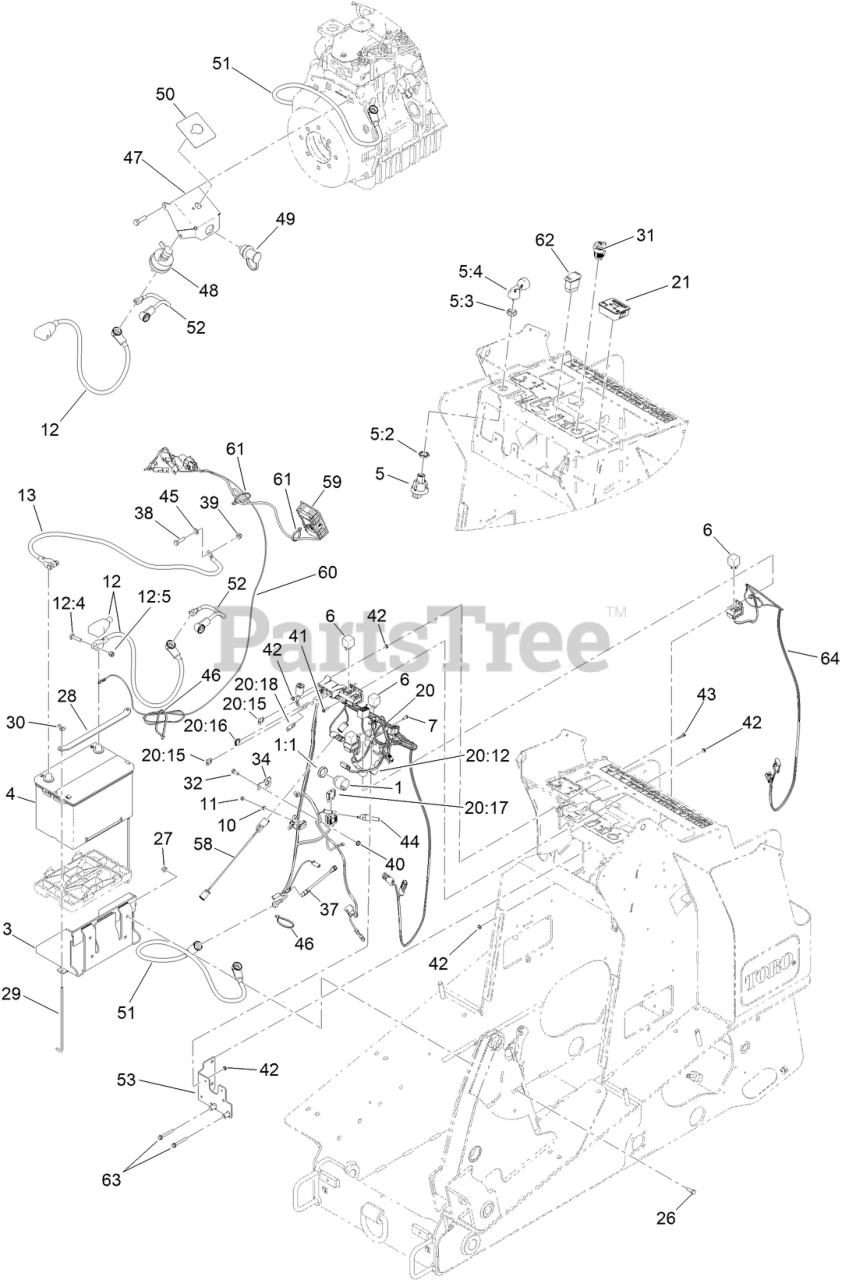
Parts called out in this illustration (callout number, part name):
1	AUDIO ALARM ASM
1:1	NUT-PLASTIC, KNURLED
3	TRAY-BATTERY
4	BATTERY
5	IGNITION SWITCH ASM
5:2	NUT-HEX
5:3	NUT-FACE
5:4	SET-KEY, IGNITION
10	WASHER-LOCK, SPRING
11	NUT-HEX
12	CABLE-BATTERY, POS ASM
12:4	BOLT-BATTERY CLAMP, 5/16-18 UNC
12:5	NUT-CLAMP, BATTERY
13	CABLE-NEGATIVE
20	HARNESS-WIRE, TX1000
20:15	FUSE-BLADE, 10 AMP
20:16	FUSE-BLADE, 15 AMP
20:17	FUSE-BLADE, 50 AMP
20:18	CAP-PLUG
21	MODULE-HOUR METER
26	SCREW-HH
27	NUT-LOCK, NI
28	STRAP-HOLD DOWN, BATTERY
29	ROD-HOLD DOWN, BATTERY
30	NUT-WING
31	RECEPTACLE-12V
32	SCREW-HH
34	CLIP-FUSE
37	HARNESS-LINK, FUSIBLE
38	SCREW-HH
39	NUT-HF, NI
40	NUT-HF
41	SCREW-HWH
42	NUT-KEPS
43	SCREW-HWHTF
44	SWITCH-TEMP
45	WASHER-PLAIN
46	TIE-CABLE
47	MOUNT-REMOTE TERMINAL
48	SWITCH-DISCONNECT, MASTER
49	STUD-JUMPER, POSITIVE
50	DECAL-BATTERY DISCONNECT
51	CABLE-BATTERY, POSITIVE
52	CABLE-BATTERY, POSITIVE
58	HARNESS-WIRE
59	M7L-LITE ZTR KIT ASM
60	HARNESS-WIRE, MACHINE ZTR
61	TIE-CABLE
62	SWITCH-INTERMITTENT
63	SCREW-HHF
64	HARNESS-WIRE, AUX HOLD
